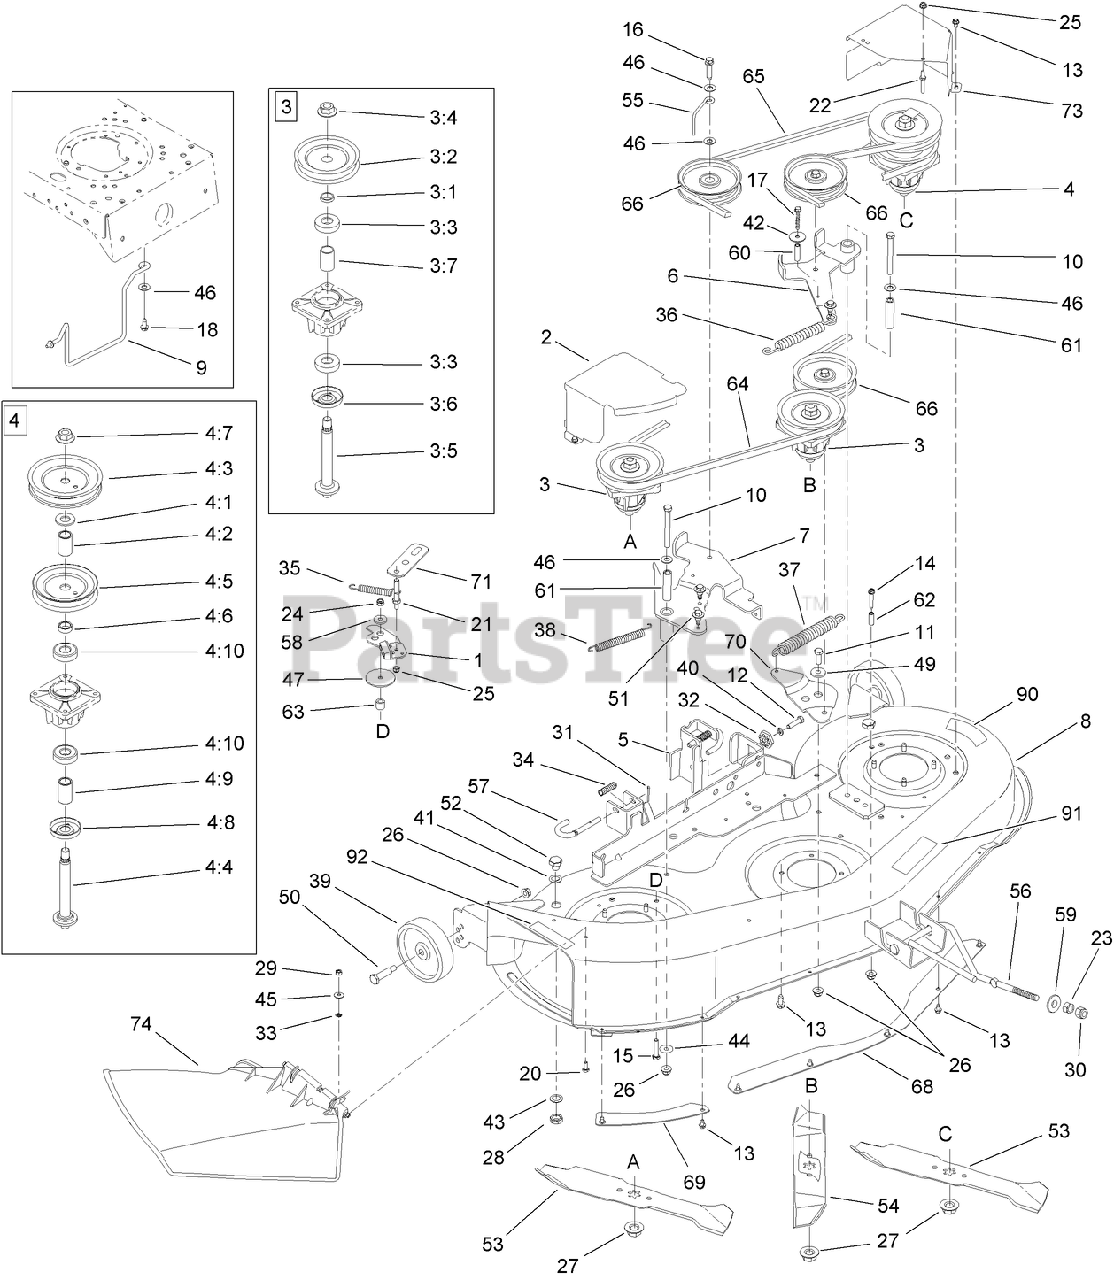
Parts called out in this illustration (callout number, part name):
1	DECK BRAKE BRACKET ASM
2	COVER-BELT, RH
3	SPINDLE ASM
3:1	SPACER
3:2	PULLEY-DECK
3:3	BEARING-BALL
3:4	NUT-LOCK, FLANGE
3:5	SHAFT-SPINDLE
3:6	BEARING-SHOULDER
3:7	SPACER
4	DOUBLE PULLEY SPINDLE ASM
4:1	WASHER-FLAT
4:2	SPACER
4:3	PULLEY-DECK
4:4	SHAFT-SPINDLE
4:5	PULLEY-DECK
4:6	SPACER
4:7	NUT-LOCK, FLANGE
4:8	BEARING-SHOULDER
4:9	SPACER
4:10	BEARING-BALL
5	LH HANGER BRACKET ASM
6	LH IDLER ARM ASM
7	BRACKET ASM
9	GUIDE-BELT, ENGINE
11	SCREW-HH
12	SCREW-HH
13	SCREW-HWHTF
14	SCREW-HWH
15	SCREW-HH
16	SCREW-TAP
17	SCREW-HH
18	SCREW-HWH
20	SCREW-HH
22	PIN-GUARD, BELT
23	NUT-HEX
24	NUT-LOCK, FLANGE
25	NUT-LOCK, FLANGE
26	NUT-LOCK, FLANGE
27	NUT-LOCK, FLANGE
28	NUT-HEX
29	NUT-HEX
30	NUT-LOCK, HEX (NYLON)
31	PIN-COTTER
32	GEAR-ADJUSTMENT, DECK
33	RETAINER-BOLT
34	SPRING-COMPRESSION
35	SPRING-EXTENSION
36	SPRING-EXTENSION
37	SPRING-EXTENSION
38	SPRING-EXTENSION
39	WHEEL-DECK, REAR
40	WASHER-LOCK
41	WASHER-FLAT
42	WASHER-FLAT
43	WASHER-LOCK
44	WASHER-FLAT
45	WASHER-SPRING
46	WASHER-FLAT
47	WASHER-FLAT
49	SPACER-SHOULDER
50	BOLT-SHOULDER
51	BOLT-SHOULDER, TAP
53	BLADE-16.28 INCH
54	BLADE-14.88 INCH
55	ROD-KEEPER, BELT
56	ROD-DECK
57	PIN-HANDLE, DECK RELEASE
58	SPACER-SHOULDER
59	CUP-PIVOT, LIFT
60	SPACER
61	SPACER
62	SPACER
63	SPACER
65	BELT-V
66	PULLEY-IDLER
68	SKIRT-CENTER, DECK
69	SKIRT-RH, DECK
70	BRACKET-IDLER
71	BRACKET BRAKE
73	COVER-BELT, LH
74	DISCHARGE CHUTE ASM
90	DECAL-DANGER
91	DECAL-ROUTING, BELT
92	DECAL-DANGER
